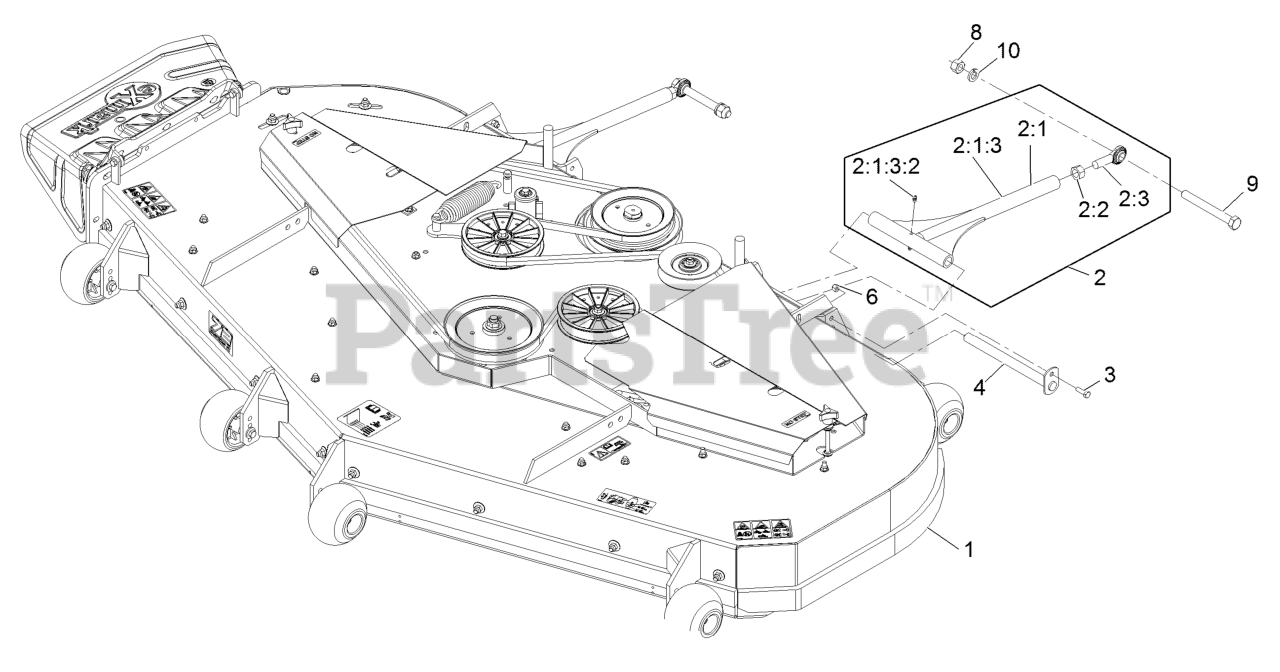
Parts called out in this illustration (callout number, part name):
1	ASM-Deck Complete 725
2	ASM,DECK STRUT XS 72
2:1	WLD,DECK STRUT
2:1:3	Tube And Zerk ASM
2:2	NUT-HEX
2:3	BALLJOINT-SPHERICAL
3	SCREW-HH
4	PIN-STRUT
6	NUT-LOCK, NI
8	NUT-HEX
9	SCREW-HH
10	WASHER-LOCK
